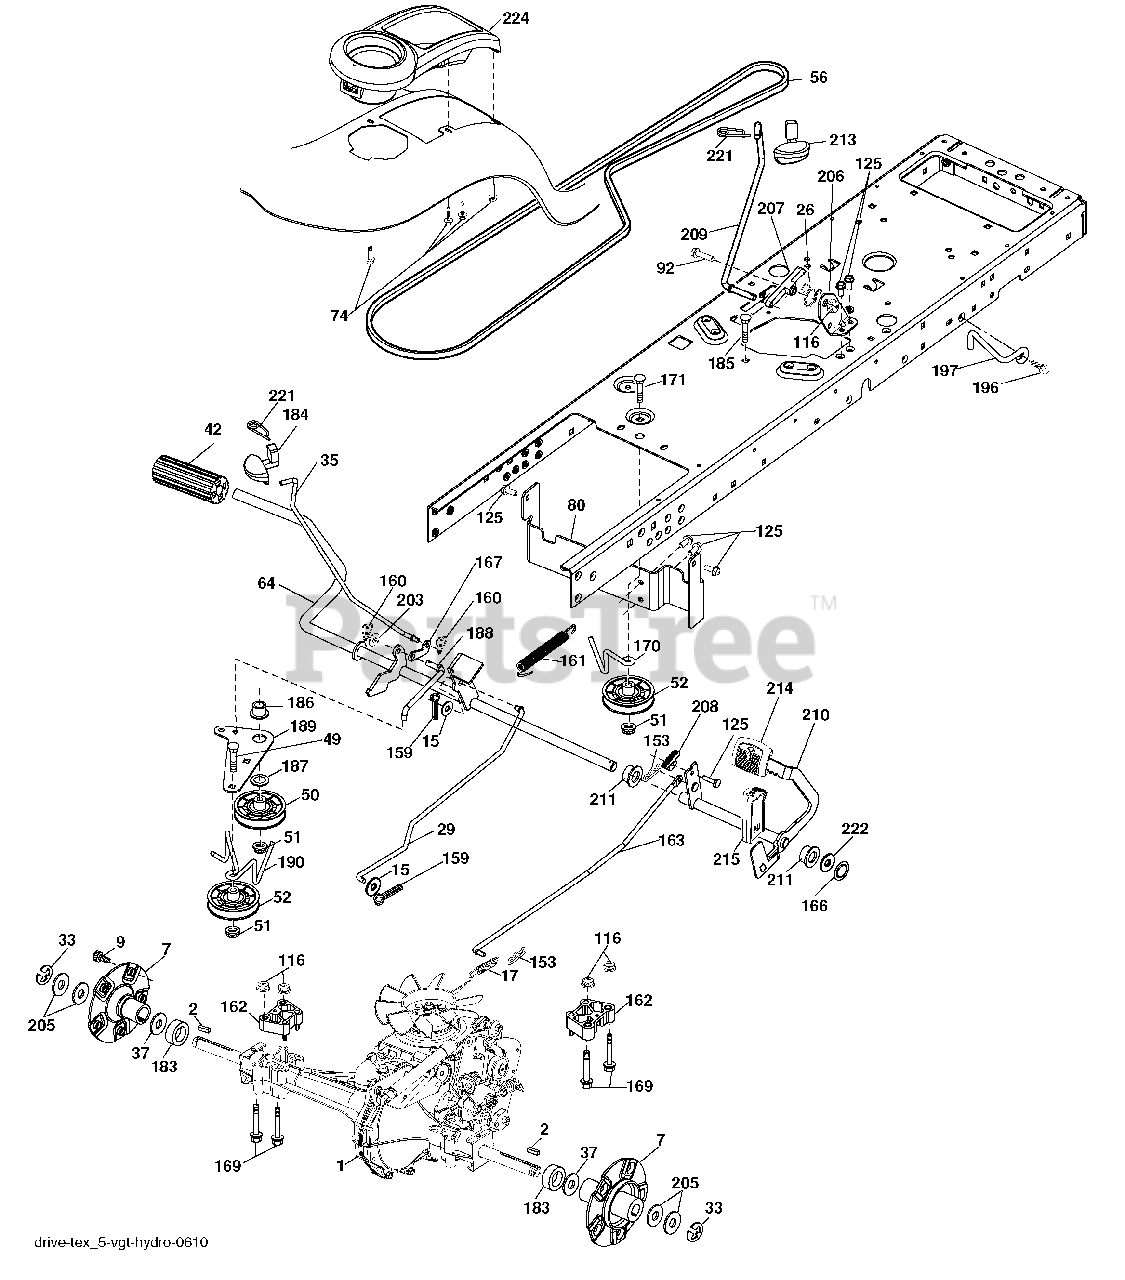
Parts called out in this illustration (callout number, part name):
2	Key 1.87 x 2.500
7	Hub Asm. Wheel
9	Bolt Hub Wheel
15	Washer 13/32 x 13/16 x 16 Ga.
17	Spring, Brake
26	Spring Return Cruise
29	Rod, Brake
33	Ring E #5133-75
35	Rod, Brake, Park
37	Washer 25/32 x 1-1/4 x 16 Ga.
42	Cover, Foot Pedal
49	Bolt
50	Pulley Idler Flat
51	Lock Nut 3/8-16
52	Idler V-Groove 910" Offset
56	V-Belt, Drive
64	Shaft Asm. Pedal Brake Control
74	Screw 1/4 x 1/2
80	Bracket Strp. Trq.
92	Bolt Fin Hex 5/16-18 unc x 1.25
116	Nut Lock Hex Flange 5/16-18
125	Screw 5/16-18 x 3/4
153	Retainer Spring 1"
159	Pin Cotter 1/8 x 3/4
160	Retainer Clip
161	Spring, Return, Clutch
162	Spacer Trans.
163	Rod Control Cruise
166	Nut Push .625
167	Latch Brake Parking
169	Bolt Hex Flngd. 5/16-18 x 3.75
170	Keeper Belt Centerspan
171	Bolt
183	Spacer Split 800 x 350.
184	Handle Parking Brake
185	Bolt
186	Spacer Retainer
187	Washer
188	Link Clutch Ground Drive
189	Bellcrank Ground Drive
190	Keeper Bellcrank Ground Drive
196	Screw 3/8-16 x 1
197	Bracket Clutch Anti-Rotation
203	Washer 11/32 x 11/16 x 16 Ga.
205	Washer 25/32 x 1-5/8 x 16 Ga.
206	Bracket Mount Latch Cruise
207	Latch Control Cruise
208	Gear Sector Control Cruise
209	Rod Control Cruise
210	Rocker Asm. Pedal Control
211	Bearing Nylon Blk .629
213	Knob Control Cruise
214	Pedal Forward
215	Pedal Reverse
221	Retainer Spring Clip Handle
222	Washer 21/32 x 1-1/4 x 10 Ga.
224	Console Toolbox
